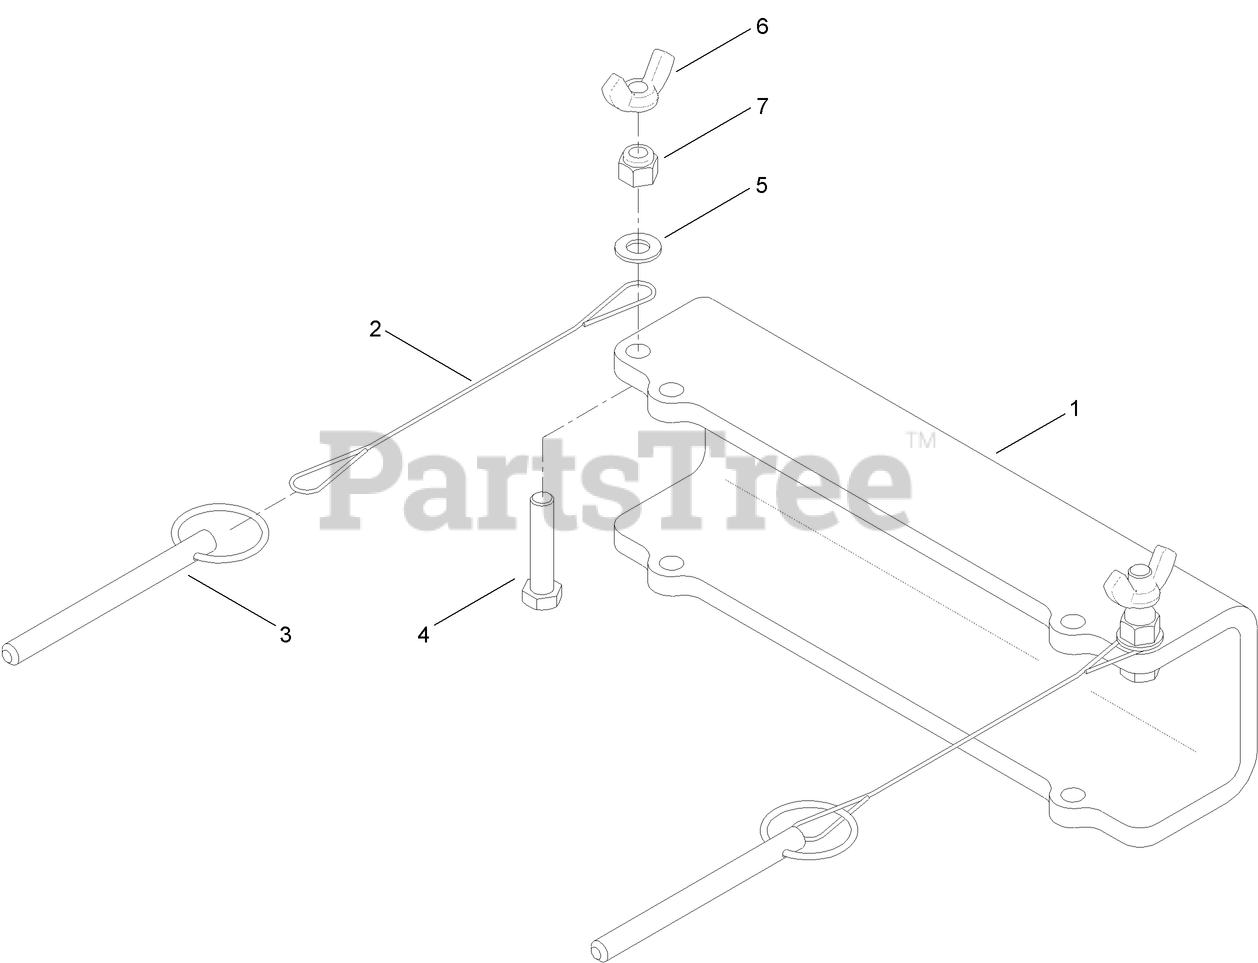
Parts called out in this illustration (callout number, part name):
1	PLATE-TILT CYLINDER LOCKOUT
2	LANYARD-TETHER, PIN
3	PIN-RETAINING
4	SCREW-HH
5	WASHER-FLAT
6	NUT-WING
7	NUT-LOCK, NI
